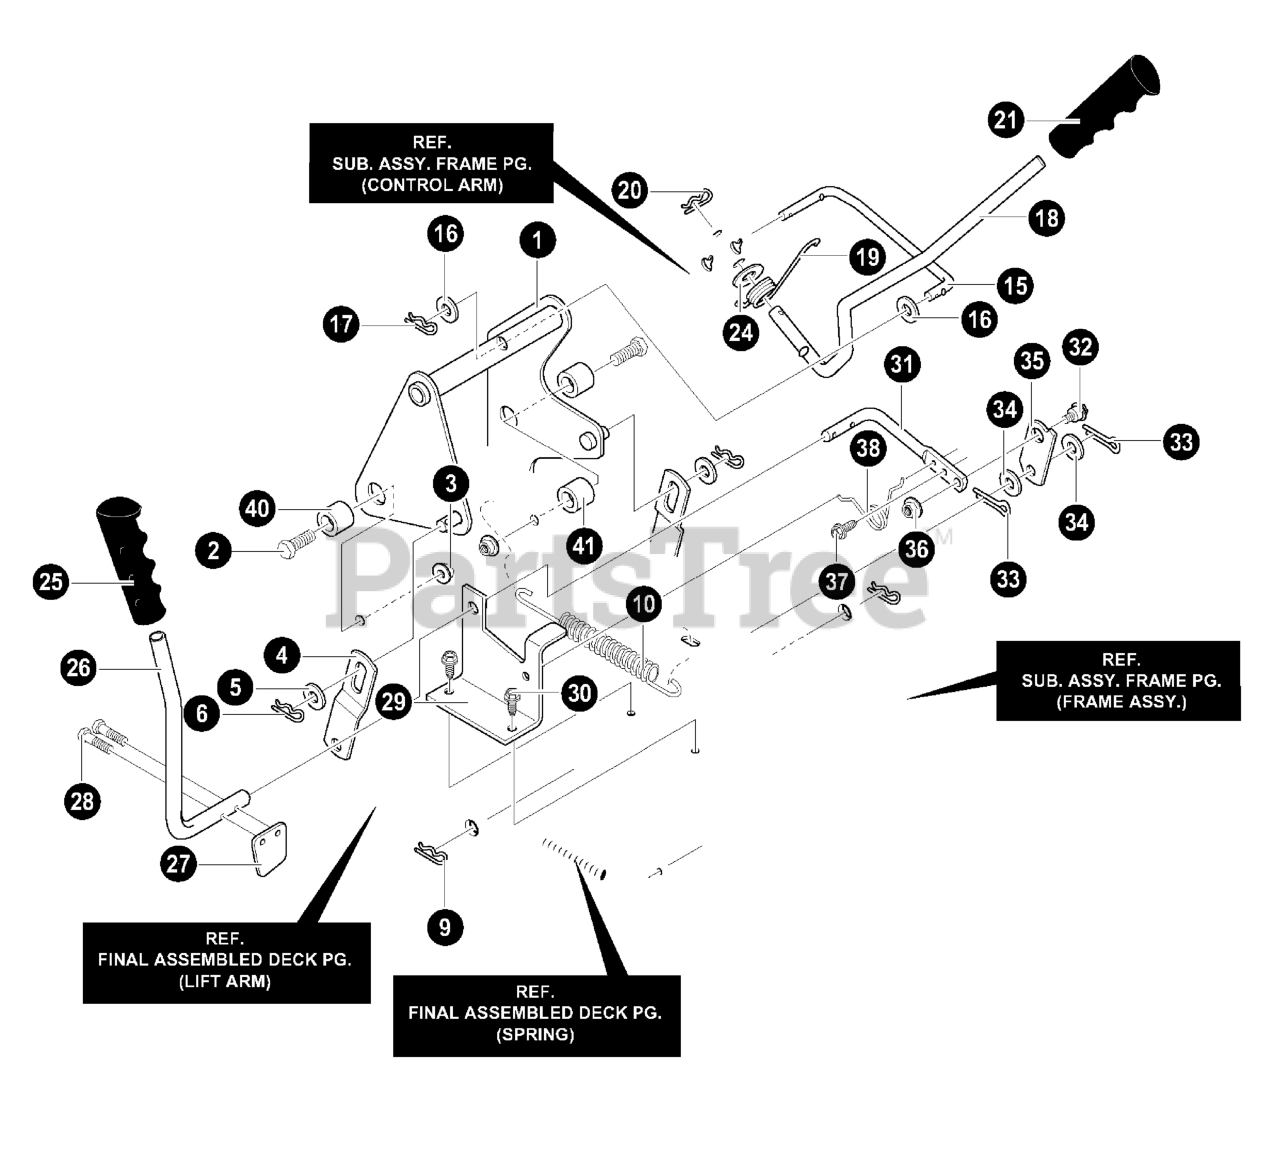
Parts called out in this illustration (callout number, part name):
1	ASSEMBLY, LIFT ARM
2	SCREW,1/2-13X1.50
3	NUT, 1/2-13 LOCK
4	BRACKET, LIFT LINK
5	WASHER,FLAT
6	PIN, HAIR
9	PIN, HAIR
10	SPRING, EXTENSION 9.82X1.01 OD
15	LINK - LIFT HANDLE
16	WASHER, FLAT
17	PIN, HAIR
18	HANDLE, LIFT
19	TORSION SPRING
20	PIN, HAIR
21	GRIP,LIFT
24	WASHER, FLAT .550X1.00X11
26	PTO HANDLE
27	ZINC PADDLE, SWITCH
28	SCREW, THREAD FORM
29	BRACKET, PTO
30	SCREW, 5/16-18 x 0.50
31	ZINC LEVER, PTO
32	BOLT, .50X.75 HHSH 3/8-16
33	PIN, HAIR
34	WASHER, FLAT .518X.87X16
35	ZINC LINK PTO
36	NUT, 3/8-16 HWDFLLK MACK
37	SCREW, 5/16-18 x 0.75
38	TORSION SPRING
40	SPACER
41	SPACER, SLEEVE
